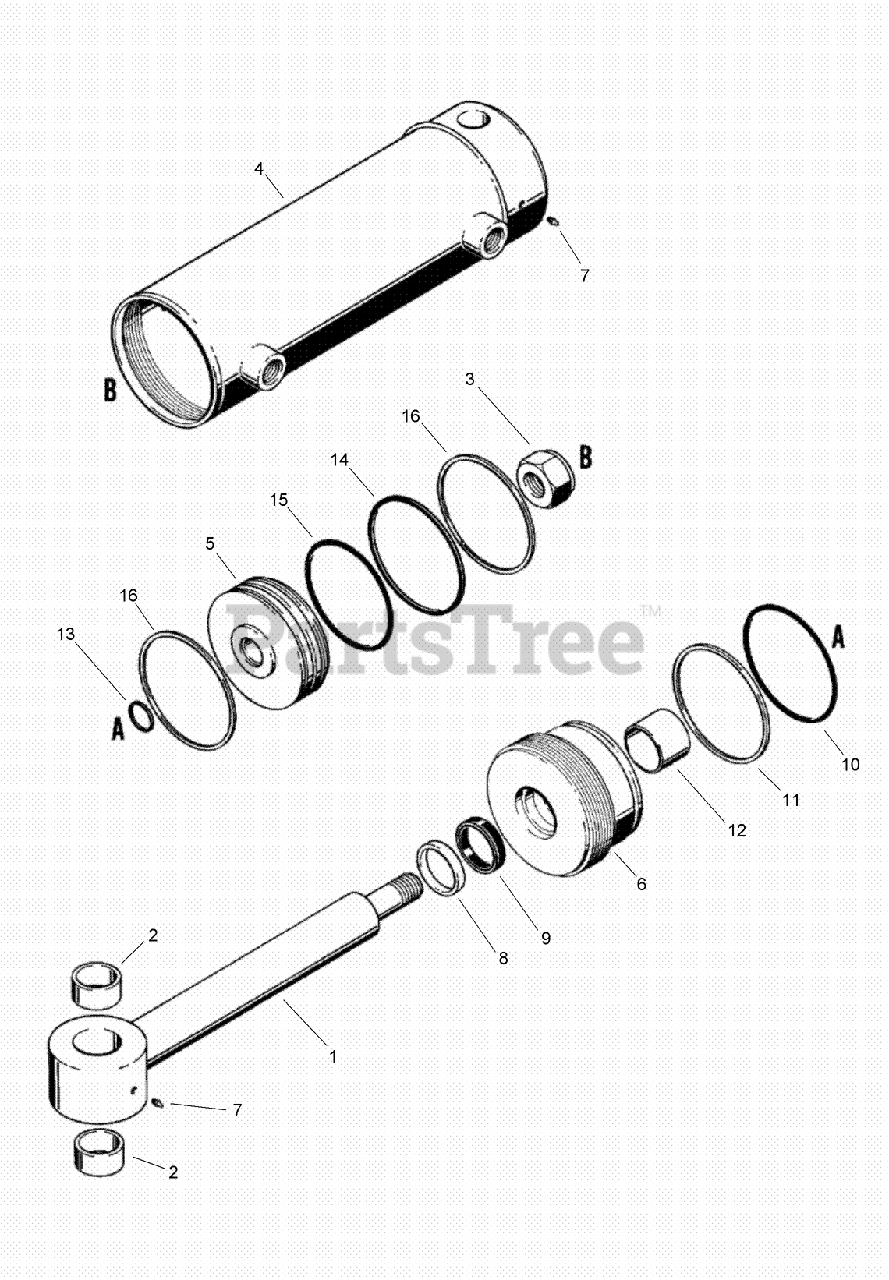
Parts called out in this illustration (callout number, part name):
1	ROD-piston
2	BUSHING-cylinder rod
3	NUT-hex, self-locking, 1-1/4 inch NF
4	TUBE-cylinder
5	PISTON-cylinder
6	GLAND-cylinder
7	FITTING-grease, straight, 1/4-28 special threads x 1/2 inch
8	WIPER-piston rod
9	Seal-U-Cup
10	O-RING-gland
11	RING-Backup, Gland
12	RING-wear, gland
13	O-RING-piston rod
14	Seal-Piston
15	O-RING-piston
16	RING-wear, piston
